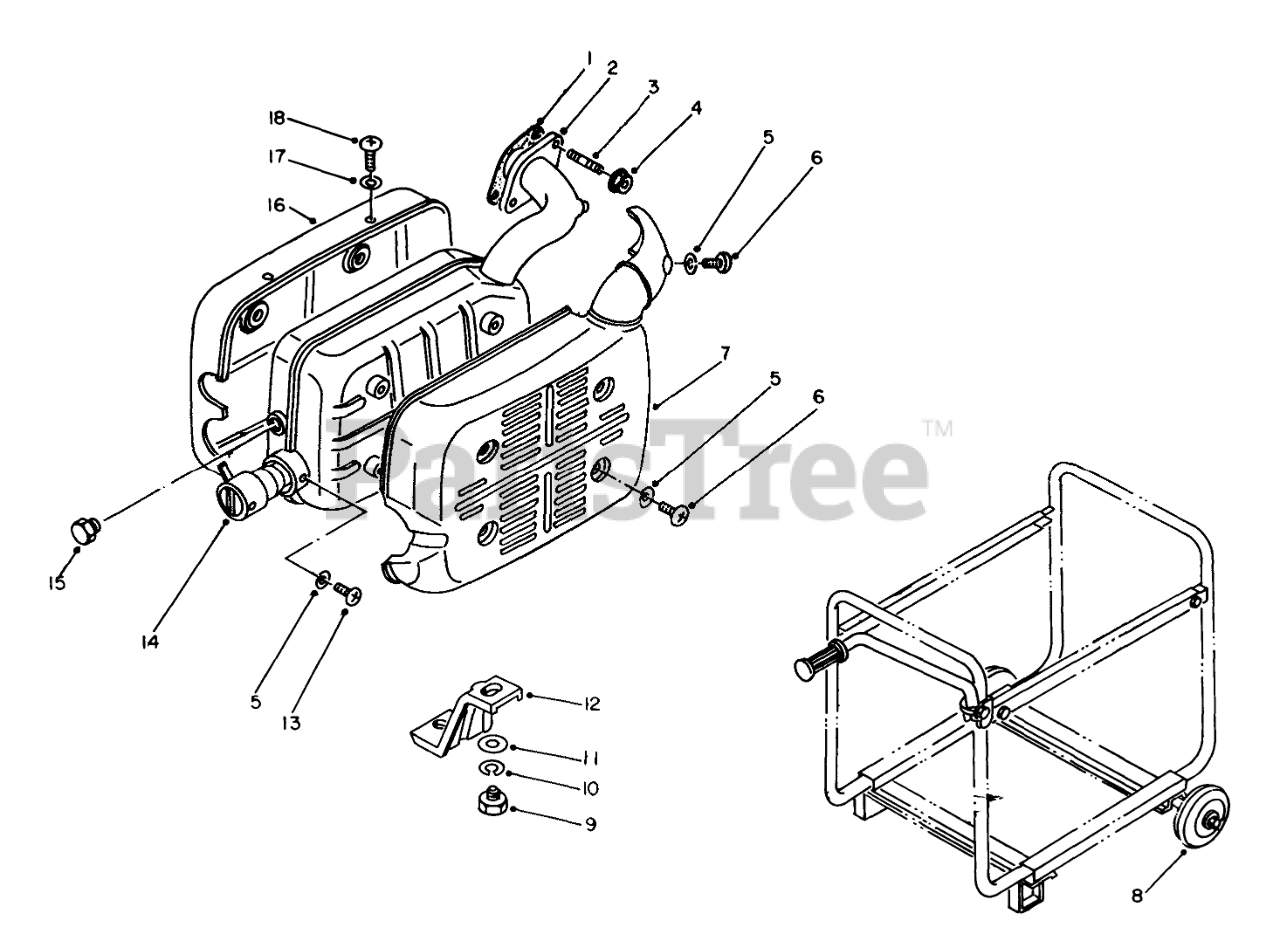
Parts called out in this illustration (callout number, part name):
2	MUFFLER ASM
6	SCREW
10	WASHER-LOCK
